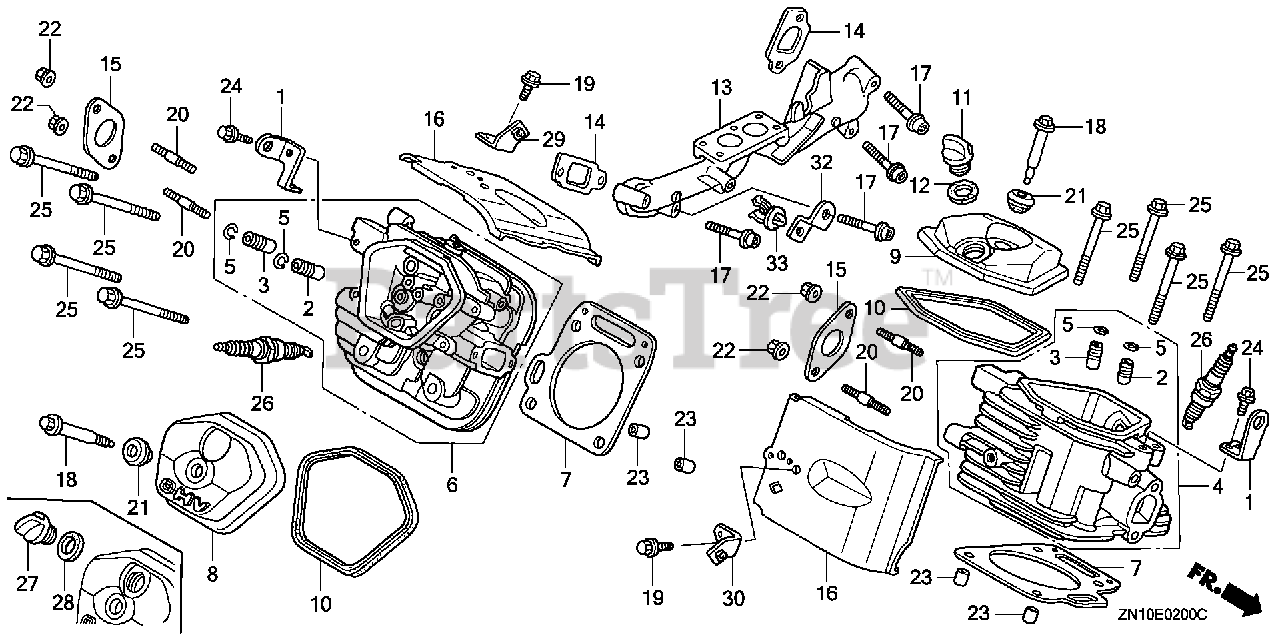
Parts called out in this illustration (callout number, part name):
1	HANGER, ENGINE
2	GUIDE, VALVE (OVER SIZE)
3	GUIDE, EX. VALVE (OVER SIZE)
4	CYLINDER HEAD (#1)
5	CLIP, VALVE GUIDE
6	CYLINDER HEAD (#2)
7	GASKET, CYLINDER HEAD
8	COVER, HEAD
9	COVER, HEAD FILLER
10	GASKET, HEAD COVER
11	CAP, OIL FILLER
12	GASKET, OIL FILLER CAP
13	MANIFOLD, IN.
14	GASKET, IN. MANIFOLD
15	GASKET, EX. PIPE
16	SHROUD, HEAD
17	BOLT, SOCKET (8X45)
18	BOLT, HEAD COVER
19	BOLT, FLANGE (6X14) (CT200)
20	BOLT, STUD (8X22)
21	WASHER, HEAD COVER
22	NUT, FLANGE (8MM)
23	PIN, DOWEL (12X20)
24	BOLT, FLANGE (8X20)
25	BOLT, FLANGE (10X80)
26	SPARK PLUG (BPR2ES) (NGK)
26	SPARK PLUG (J14CR-U) (DENSO)
26	SPARK PLUG (ZGR4A)
26	SPARK PLUG (J16CR-U) (DENSO)
26	SPARK PLUG (ZGR5A)
